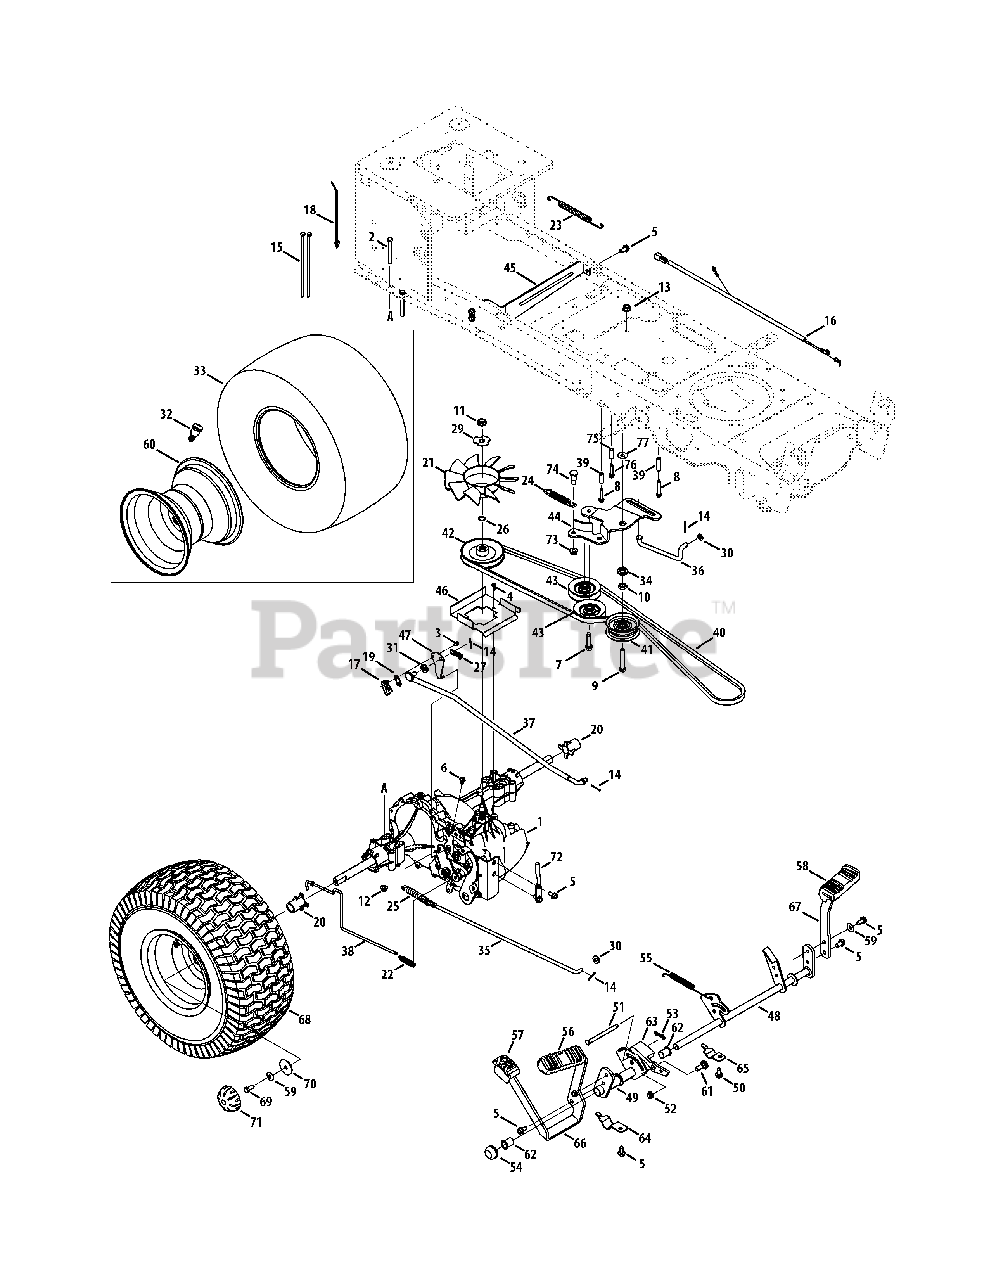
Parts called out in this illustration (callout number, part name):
1	Hydro Transmission
2	Hex Head Screw, 5/16-18:2.75
3	Screw, Indented Washer, #8-18:0.500
4	Screw, #10-16:0.500
5	Taptite Screw, Indented Washer, 5/16-18:.750
6	Taptite Screw, Indented Washer, 1/4-20:0.375
7	Taptite Sems Screw, :3/8-16:1.500
8	Taptite Screw, Indented Washer, 1/4-20:1.625
9	Hex Head Screw, 3/8-16:2.25
10	Jam Nut, 7/16-20
11	Jamlock Nut, 1/2-20
12	Flangelock Nut, 5/16-18
13	Flangelock Nut, 3/8-16
14	Cotter Pin, 3/32:1.0
15	Cable Tie. 3/16 X .05 X 7.4
16	Jumper Harness
17	Short Spring Switch
18	Push Mount Cable Tie 7.5 LG
19	Insulator Nut Plate
20	Sleeve, .765 ID X 1.500 LG
21	Hydro Fan
22	Extension Spring, .48 OD X 2.03
23	Extension Spring, .500 DIA X 12.6 LG
24	Extension Spring, 1.00 DIA X 4.75
25	Extension Spring, .59 OD X 4.00 LG
26	Wire Ring
27	Extension Spring, .375 OD X 1.44 LG
28	Flat Washer, .330 X .630 X .0635
29	Lock Washer
30	Flat Washer, .344 X .750 X .120
31	Flat Washer, .407 X .812 X .135
32	Tubeless Air Valve
34	Shoulder Spacer, 1.375 X .380 X .183
35	Brake Rod
36	Footpedal Bypass Transmission Rod
37	Hydro Control Rod
38	Hydro Bypass Rod
39	Spacer, 260 X .372 X 1.420 LG
40	V-Belt, 4L X 78.9 POLY
41	Flat Idler Pulley, 2.75 OD
42	Input Pulley, 4.13 DIA
43	V Idler Pulley, X 3.06
44	Center Idler Bracket
45	Hydro Mounting Bracket
46	Belt Disengage Support Bracket
47	Switch Actuator Bracket
48	Brake Control Assembly
49	Hydro Pedal Bracket Assembly
50	Taptite Screw, Indented Washer, 5/16-18:0.625
51	Clevis Pin, 5/16 X 3.985
52	Flangelock Nut, 3/8-16
53	Bow-Tie Cotter Pin
54	Push Cap
55	Extension Spring, .63 DIA X 4.95 LG
56	Forward Pedal Pad
57	Reverse Pedal Pad
58	Brake Pedal Pad
59	Bell Washer, .340 X .872 X .060
60	Rim Assembly
61	Shoulder Bolt, .500 X .270:3/8-16
62	Flange Bearing, .630 IDX .695 OD X .60
63	Cruise Latch
64	Pedal Support Bracket
65	Pedal Support Bracket, 5/8
66	Drive Pedal Bracket
67	Brake Pedal Bracket
68	Wheel Assembly
69	Hex Head Screw, 5/16-24:.750
70	Flat Washer, .350 x 1.59 x .062
71	Hub Cap
72	Belt Keeper Rod
73	Flangelock Nut, 3/8-16
74	Shoulder Screw, .50 x .685:3/8-16
75	Spacer, 260 X .375 X 1.030 LG
76	Taptite Screw, Indented Washer, 1/4-20:0.375
77	Flat Washer, .385 X 1.00 X .030
